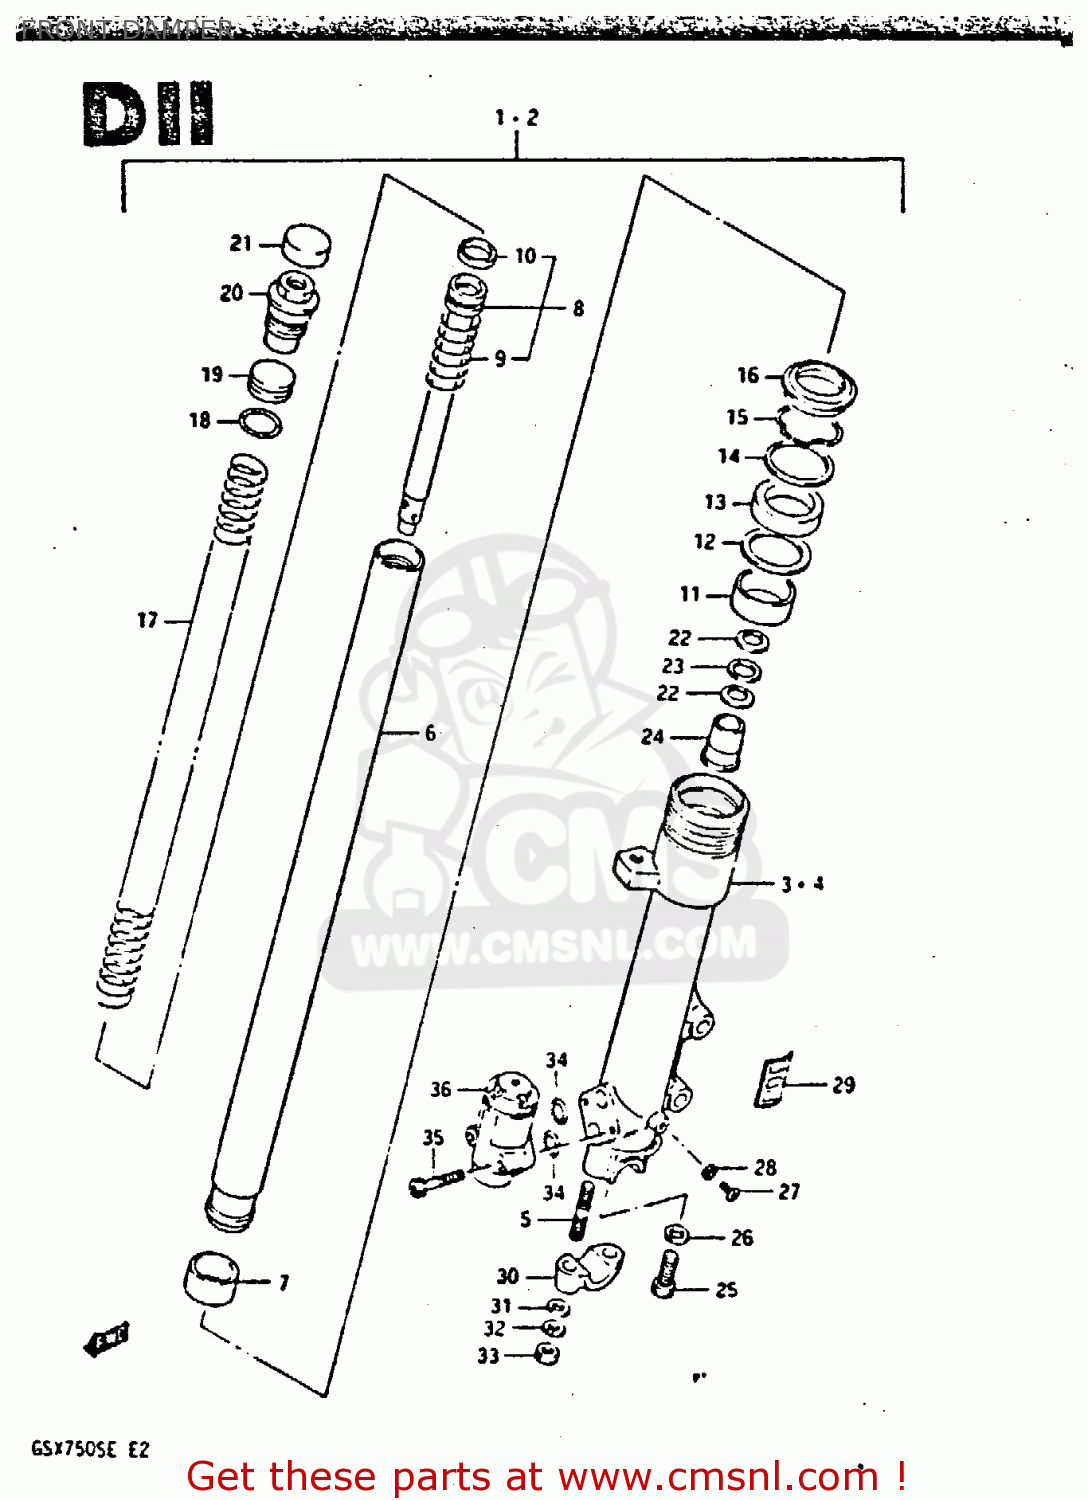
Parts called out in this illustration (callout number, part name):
1	DAMPER ASSY, RH
2	DAMPER ASSY, LH
3	OUTER TUBE, RH (BLACK)
4	OUTER TUBE, LH (BLACK)
5	STUD 8X30
6	TUBE,INNER
7	METAL,FR FORK PISTON
8	CYLINDER
9	SPRING,REBOUND
10	RING,FR FORK PISTON
11	METAL,SLIDE
12	WASHER
13	SEAL,OIL
14	WASHER,FORK OIL SEAL
15	RING,STOPPER
16	SEAL,DUST
17	SPRING
18	O-RING
19	PISTON,FREE
20	CAP
21	CAP,FORK INNER TUBE
22	SPRING,LEAF
23	WASHER
24	PIECE,OIL LOCK
25	BOLT,FORK CYLINDER(10X25)
26	GASKET (NAS)
27	SCREW
28	GASKET,DRAIN,PLUG (NAS)
29	EMBLEM
30	HOLDER,AXLE
31	WASHER
32	WASHER,LOCK,8.
33	NUT
34	O RING
35	BOLT
36	P.D.F ASSY
